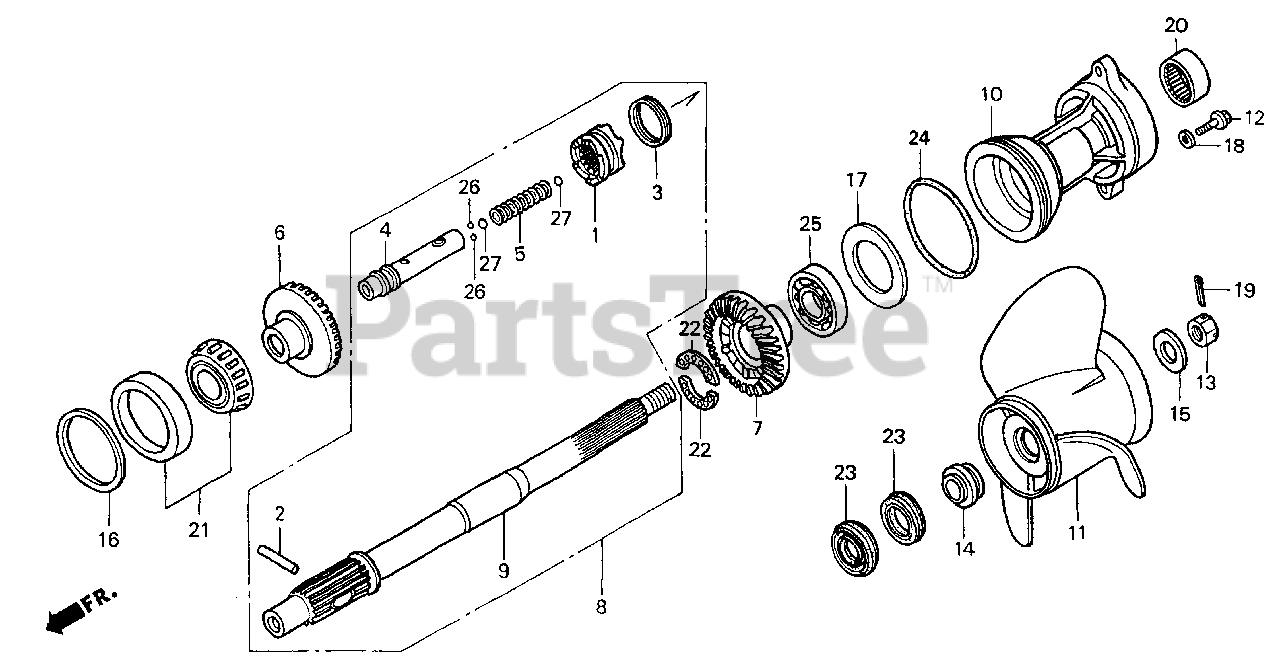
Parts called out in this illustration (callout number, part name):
1	SHIFTER, CLUTCH
2	PIN, SHIFTER (8X47)
3	RING, CROSS PIN
4	SLIDER, SHIFT
5	SPRING, SHIFT
6	GEAR, BEVEL (F)
7	GEAR, BEVEL (R)
8	SHAFT ASSY., PROPELLER
9	SHAFT, PROPELLER
10	HOLDER, PROPELLER SHAFT *NH282MU* (OYSTER SILVER METALLIC-U)
11	PROPELLER, THREE-BLADE (13-1/8X16) (SUS) Use up to Frame SN 1302159.
11	PROPELLER, THREE-BLADE (13X18) (SUS) (NOT AVAILABLE) Use up to Frame SN 1302131.
11	PROPELLER, THREE-BLADE (13-1/4X20) (SUS) (NOT AVAILABLE) Use up to Frame SN 1302131.
11	PROPELLER, THREE-BLADE (13-1/2X22) (SUS) (NOT AVAILABLE) Use up to Frame SN 1302127.
11	PROPELLER, THREE-BLADE (14X11) *NH105* (AL) (MAT BLACK) Use up to Frame SN 1302159.
11	PROPELLER, THREE-BLADE (14X13) *NH105* (AL) (MAT BLACK) Use up to Frame SN 1302159.
11	PROPELLER, THREE-BLADE (13-3/4X15) *NH105* (AL) (MAT BLACK) Use up to Frame SN 1302159.
11	PROPELLER, THREE-BLADE (13-1/4X17) *NH105* (AL) (MAT BLACK) Use up to Frame SN 1302159.
11	PROPELLER, THREE-BLADE (12-3/4X21) *NH105* (AL) (MAT BLACK) Use up to Frame SN 1302159.
11	PROPELLER, THREE-BLADE (12-1/2X23) *NH105* (AL) (MAT BLACK) Use up to Frame SN 1302127.
11	PROPELLER, THREE-BLADE (13X19) *NH105* (AL) (MAT BLACK) Use up to Frame SN 1302159.
11	PROPELLER, THREE-BLADE (13X19) (SUS) Use from Frame SN 1302132.
11	PROPELLER, THREE-BLADE (13X21) (SUS) Use from Frame SN 1302132.
11	PROPELLER, THREE-BLADE (14X11) *NH283* (AL) Use from Frame SN 1302160.
11	PROPELLER, THREE-BLADE (13-3/4X13) *NH283* (AL) Use from Frame SN 1302160.
11	PROPELLER, THREE-BLADE (13-1/2X15) *NH283* (AL) Use from Frame SN 1302160.
11	PROPELLER, THREE-BLADE (13-1/4X17) (AL) Use from Frame SN 1302160.
11	PROPELLER, THREE-BLADE (13-1/4X17) *NH283* (AL) Use from Frame SN 1302160.
11	PROPELLER, THREE-BLADE (13X21) *NH283* (AL) Use from Frame SN 1302160.
11	PROPELLER, THREE-BLADE (13X19) (AL) Use from Frame SN 1302160.
11	PROPELLER, THREE-BLADE (13-1/4X17) (SUS) Use from Frame SN 1302160.
12	BOLT, HEX. (10X40)
13	NUT, CASTLE (18MM)
14	WASHER, PROPELLER THRUST
15	WASHER, PLAIN (18.5MM)
16	SHIM A, BEVEL (0.10) (FR)
16	SHIM B, BEVEL (0.15) (FR)
16	SHIM C, BEVEL (0.30) (FR)
16	SHIM D, BEVEL (0.50) (FR)
17	SHIM A, BEVEL GEAR (0.10) (RR)
17	SHIM B, BEVEL GEAR (0.15) (RR)
17	SHIM C, BEVEL GEAR (0.30) (RR)
17	SHIM D, BEVEL GEAR (0.50) (RR)
18	WASHER, PLAIN (10MM)
19	PIN, SPLIT (4.0)
20	BEARING, NEEDLE (30X37X26)
21	BEARING, TAPERED (50X82X21.5)
22	BEARING, BALL (28X38X3)
23	SEAL, WATER (30X45X7)
24	O-RING (94X4.1)
25	BEARING, RADIAL BALL (6208)
26	BALL, STEEL (#6) (3/16)
27	BALL, STEEL (#11) (11/32)
